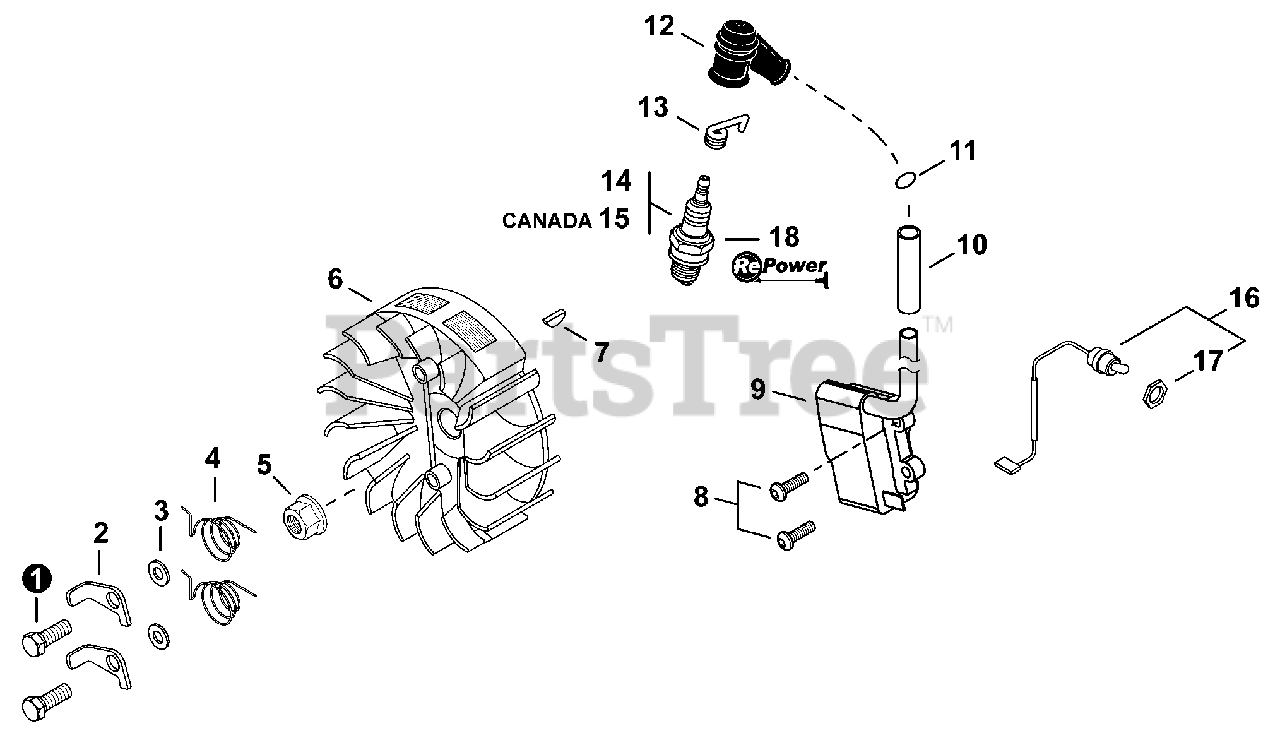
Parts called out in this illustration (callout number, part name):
3	WASHER 6
4	SPRING, TORSION
5	NUT M8×1.0
6	FLYWHEEL
7	KEY, WOODRUFF 3×10
8	BOLT, ADHESIVE M4×20
9	COIL ASSY, IGNITION
10	SLEEVE, INSULATOR
11	O-RING 7
12	CAP, SPARK PLUG
13	TERMINAL, SPARK PLUG
14	SPARK PLUG - BPM8Y
15	SPARK PLUG - BPMR8Y
16	SWITCH ASSY, ON-OFF
18	TUNE-UP KIT - REPOWER
